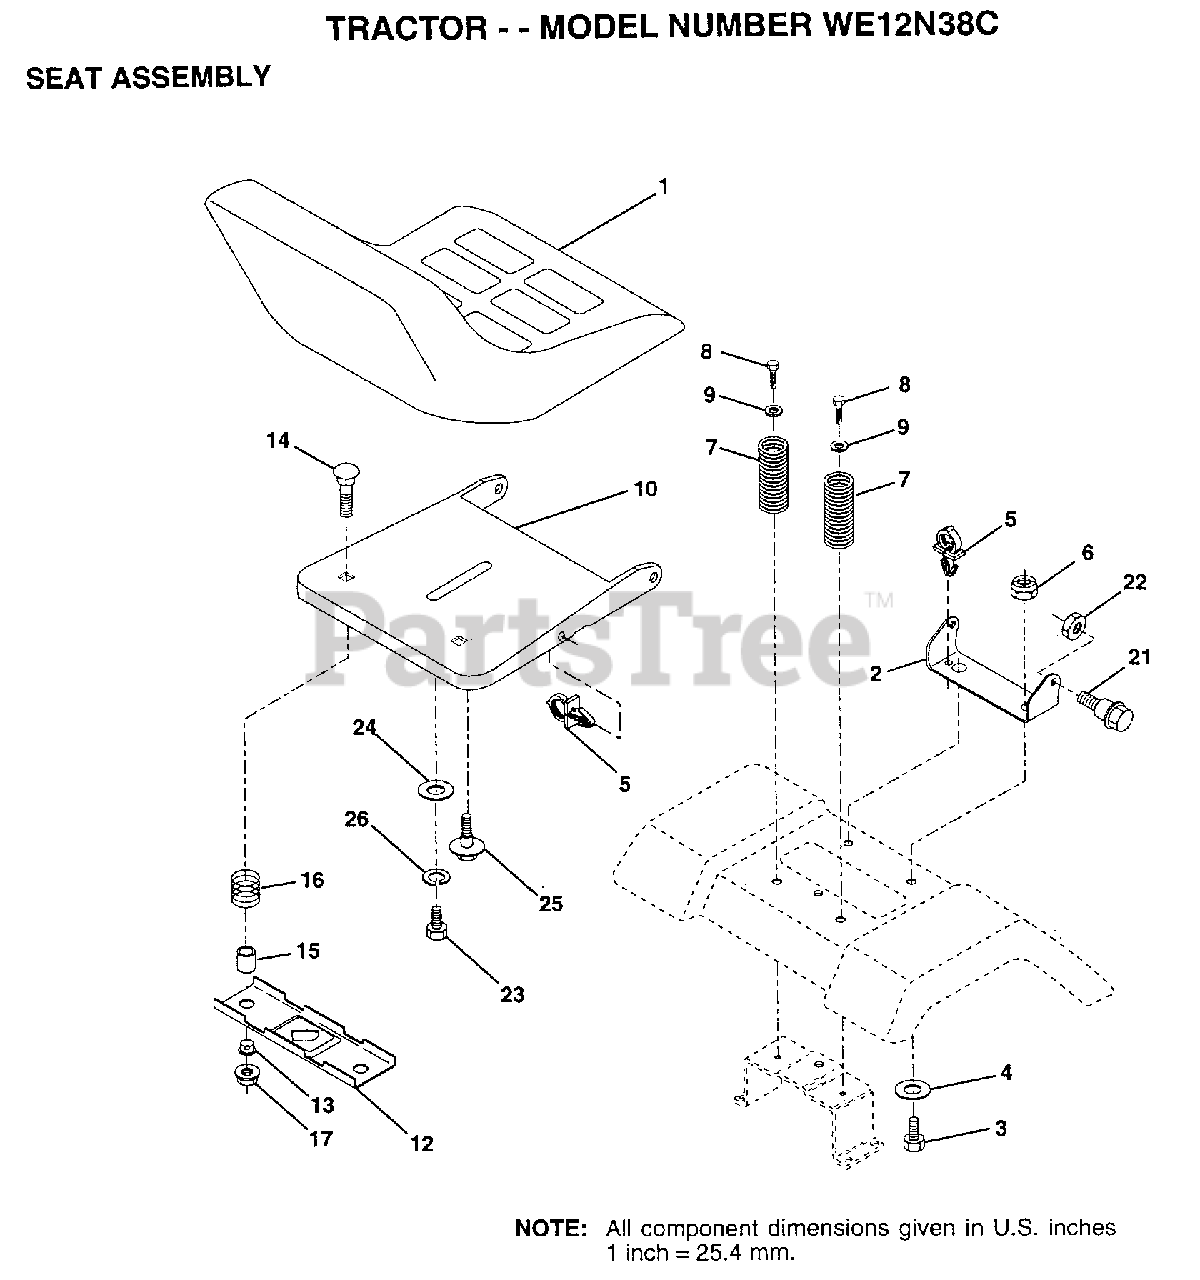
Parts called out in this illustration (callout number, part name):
2	BRACKET PVT SEAT
3	BOLT
4	WASHER PM
5	CLIP.PUSH-IN.HING
6	NUT
7	SPRING COMPRESSIO
8	SCREW GTV
9	WASHER
12	BRKT SWITCH
13	BUSHING
15	SPLIT SPACER
16	SPRING
21	"BOLT,SHOULDER"
22	NUT
23	BOLT
24	WASHER
25	"BOLT,SHOULDER"
26	LOCKWASHER
